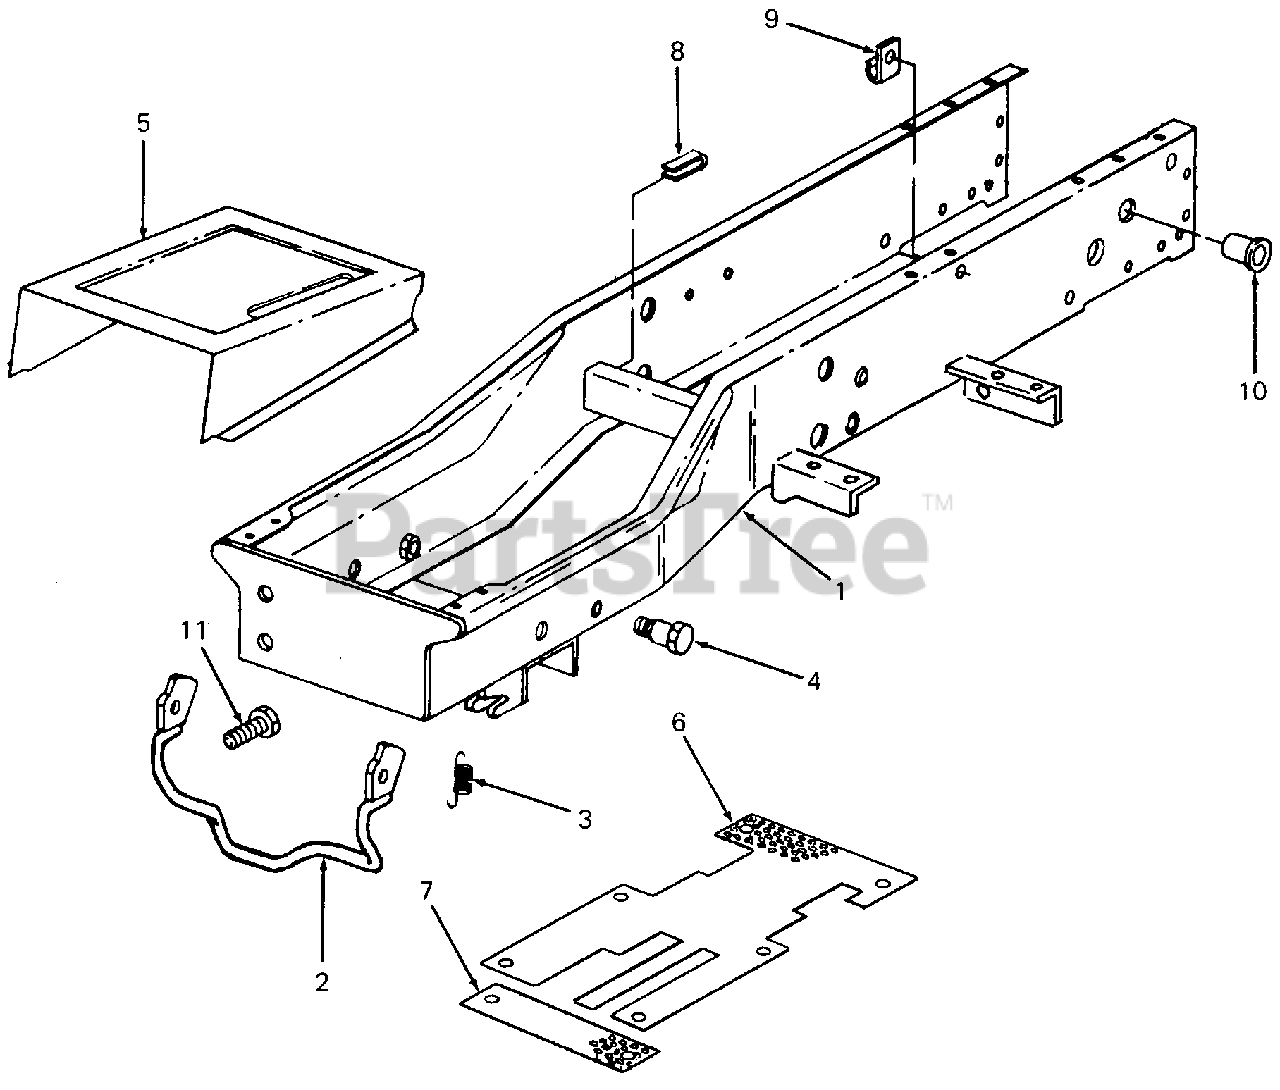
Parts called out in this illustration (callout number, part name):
1	Frame Assy
3	Spring, Latch
4	Bolt, Shoulder
5	Cover, Frame w/Graphic
6	Screen, Lower Frame
7	Screen, Front Lower Frame
8	Clip, Steering Bracket Cable
9	Clip, Cable
10	Bushing, Snap
11	Screw, Adjustment, 1/2-20 X 1.0 Lg GR5
